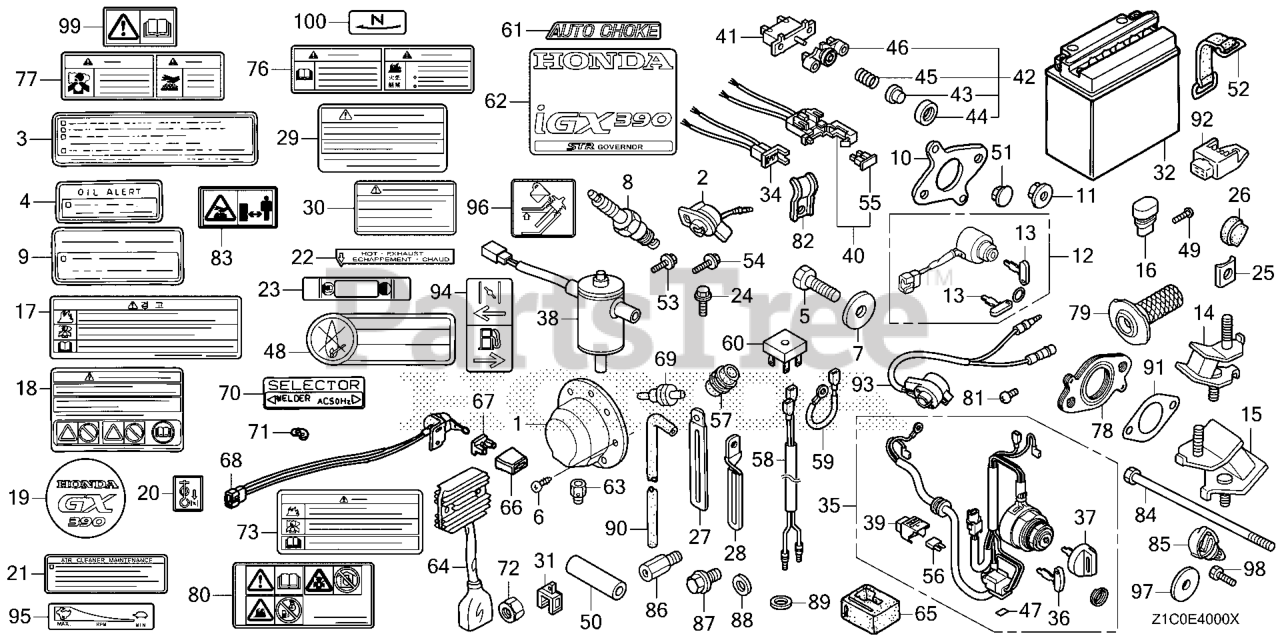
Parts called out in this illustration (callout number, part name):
29	MARK, OPERATOR CAUTION (FRENCH)(MADE IN THAI)
29	MARK, OPERATOR CAUTION (ENGLISH)(MADE IN THAI)
30	MARK, EX. CAUTION (FRENCH)
30	MARK, EX. CAUTION (ENGLISH)
54	BOLT, FLANGE (8X32)
76	MARK A, COMBINATION (JAPANESE)
77	MARK B, COMBINATION (JAPANESE)
80	MARK, OPERATOR CAUTION (PICTOGRAPH)
81	SCREW, PAN (5X12)
82	HOLDER, CONTROL CABLE
83	MARK, EX. CAUTION (PICTOGRAPH)
